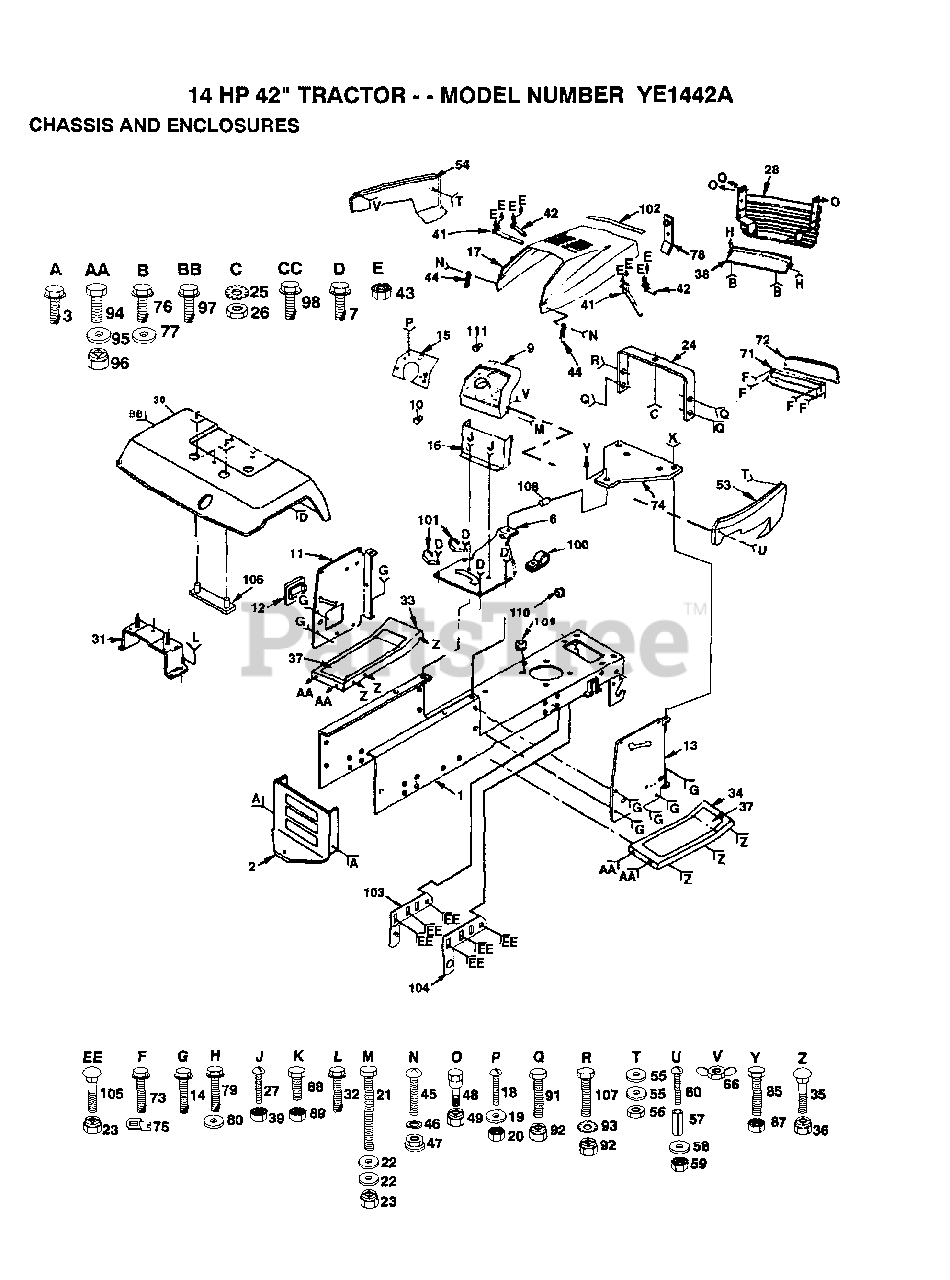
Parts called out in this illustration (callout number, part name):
3	SCREW
7	SCREW LT
10	PLUG BUTTON T
11	PANEL DASH LH
12	COVER ACCESS
13	DASH PANEL RH
14	SCREW
16	DASH ASSY LT
18	SCREW
19	WASHER
22	WASHER
24	SUPPORT ASS'Y
27	SCREW
30	FENDER
32	SCREW
35	BOLT
37	FOOTREST PAD
43	NUT
44	HOOD LATCH T
45	SCREW
46	LOCKWASHER
47	WELDNUT
53	"PANEL,SIDE RH"
54	"PANEL,SIDE LH"
55	WASHER PM
57	SPACER LT
58	WASHER
60	SCREW
72	LENS LT
75	"""J"" FASTENER LT"
76	SCREW
77	WASHER
79	SCREW HEX CRT
80	WASHER
85	BOLT
89	NUT
93	LOCKWASHER
95	WASHER
97	SCREW LT
100	CLIP T
101	CLIP T
103	PIVOT BRKT LH
104	PIVOT BRKT RH
105	BOLT
107	BOLT
108	SPACER
109	SNAP BUSHING T
111	PLUG-DASH T
